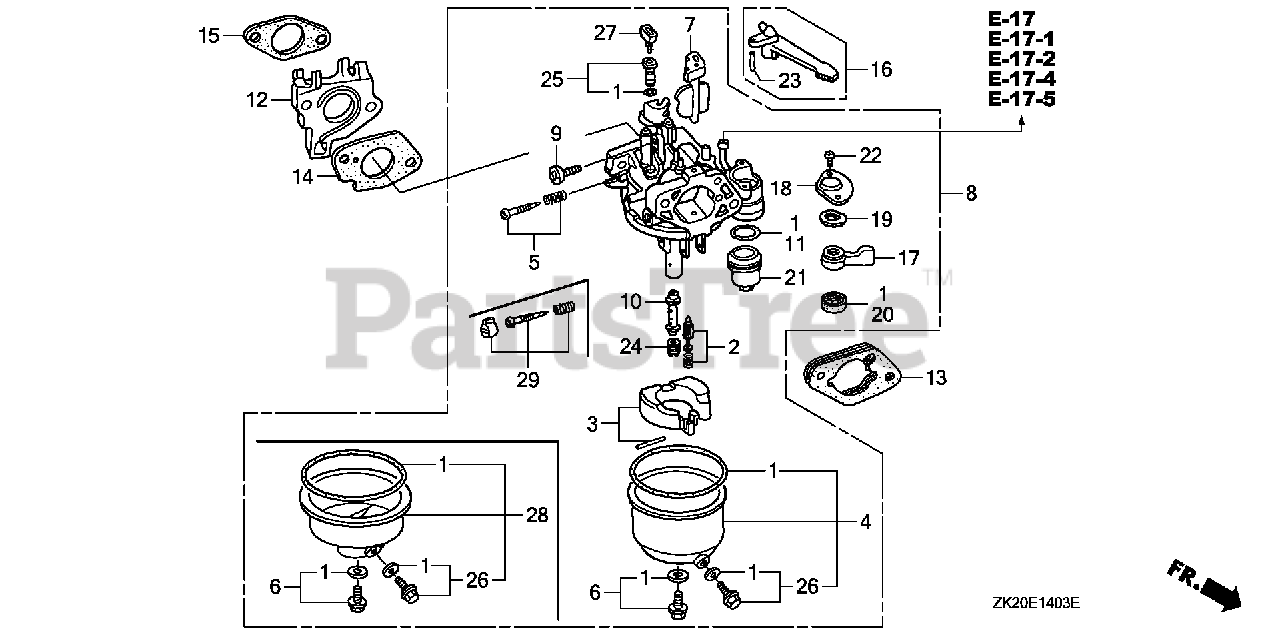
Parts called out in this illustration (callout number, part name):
1	GASKET SET (INCLUDES 16173-001-004)
2	VALVE SET, FLOAT
4	CHAMBER SET, FLOAT
6	SCREW SET
8	CARBURETOR ASSY. (BE70B B/C)
9	SCREW, THROTTLE STOP
10	NOZZLE, MAIN (CARBURETOR NO.)
11	GASKET, FUEL STRAINER CUP
12	INSULATOR, CARBURETOR
13	SPACER, CARBURETOR
14	GASKET, CARBURETOR
15	GASKET, INSULATOR
16	LEVER, CHOKE (STD)
17	LEVER, PETCOCK (CARBURETOR NO.)
18	PLATE, LEVER SETTING (CARBURETOR NO.)
19	SPRING, PETCOCK LEVER
20	GASKET, PETCOCK
21	CUP, FUEL STRAINER
22	SCREW, PAN (3X6)
23	PIN, SPRING (2X12)
24	JET, MAIN (#82) (CARBURETOR NO.)
24	JET, MAIN (#85) (CARBURETOR NO.)
24	JET, MAIN (#88) (CARBURETOR NO.)
25	JET SET, PILOT (#40) (CARBURETOR NO.)
26	SCREW SET, DRAIN (CARBURETOR NO.)
27	COLLAR, SETTING (CARBURETOR NO.)
28	CHAMBER SET, FLOAT (CARBURETOR NO.)
29	SCREW SET, PILOT (CARBURETOR NO.)
